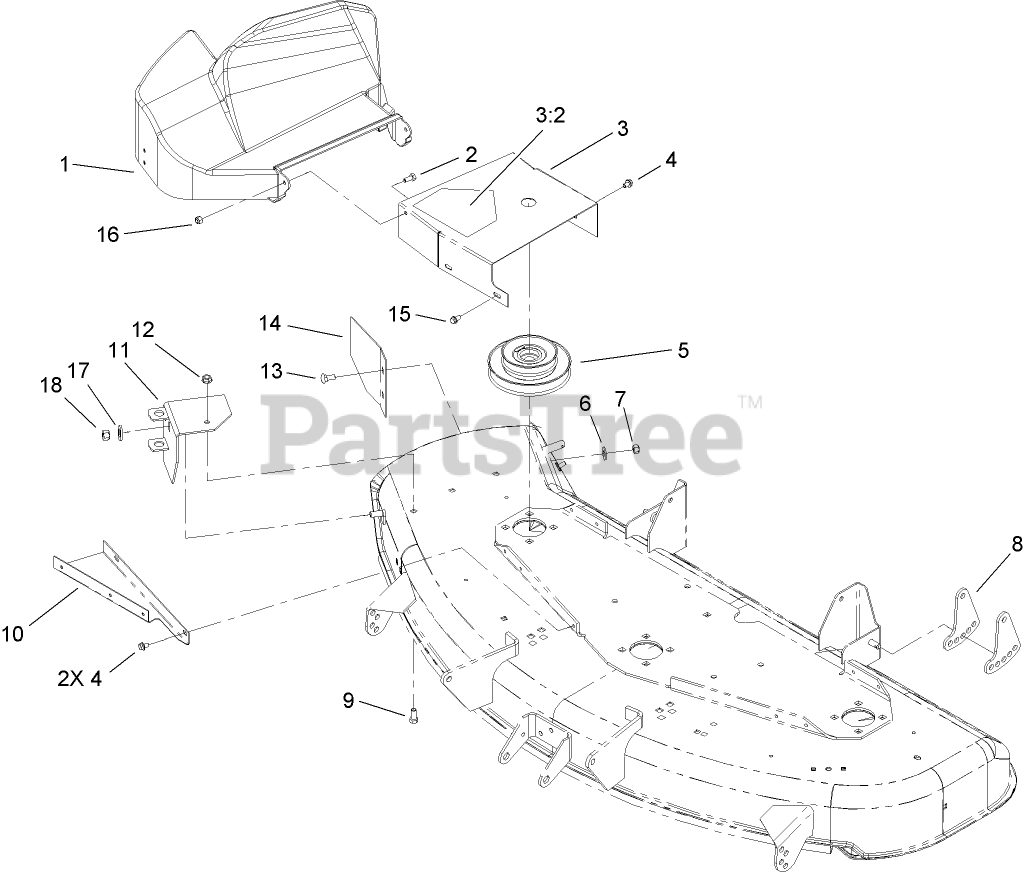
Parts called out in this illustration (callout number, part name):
1	BELT SHIELD ASM
2	SCREW-HH
3	COVER ASM
3:2	DECAL-DANGER, SHIELD
4	SCREW-HHF
5	PULLEY
6	WASHER-FLAT
7	NUT-LOCK, NI
8	LINK-ADJUSTING, HOC
9	SCREW-HH
10	ADAPTER-SHIELD
11	PIVOT BRACKET ASM
12	NUT-HF
13	BOLT-CARR
15	SCREW-HWH
16	NUT-LOCK, NI
17	WASHER-FLAT
18	NUT-HJ
